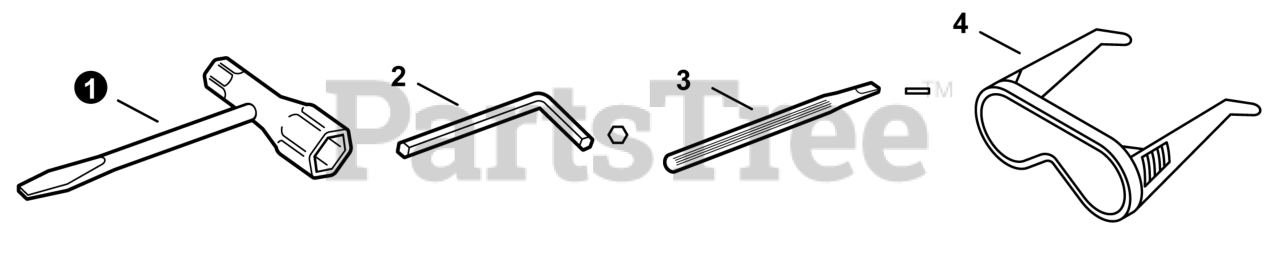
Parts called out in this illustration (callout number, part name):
1	T-WRENCH 13×19 L= 180
2	WRENCH, ALLEN 4 MM
3	SCREWDRIVER, PLASTIC
4	GLASSES, SAFETY
